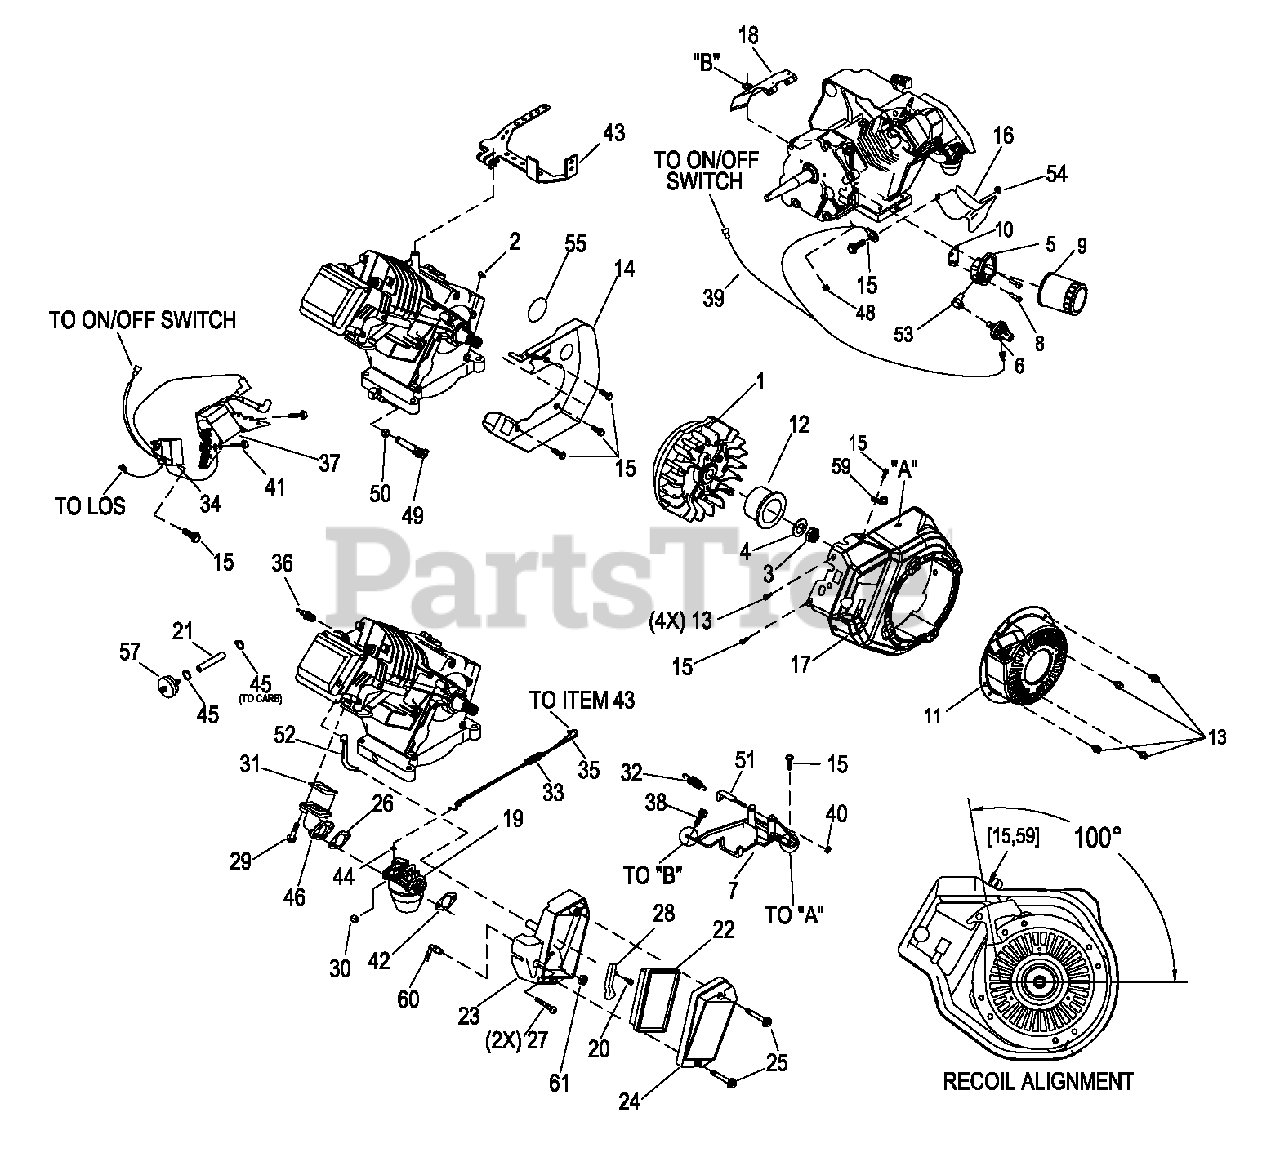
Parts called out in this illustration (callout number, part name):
1	ASSY, FLYWHEEL 29 DEGREE
2	KEY, WOODRUFF 4 X 19 DIAMETER
3	NUT, HEX M16-1.5 G8
4	WASHER, M16 CONICAL
5	ADAPTOR, OIL FILTER GH220
6	OIL PRESSURE SWITCH 5PSI
7	ASSY, BRACKET GOVERNOR ADJUSTMENT
8	SCREW, SHC M6-1.0 x 20
9	OIL FILTER BLACK 75mm LONG
10	GASKET, OIL PSI
11	ASSEMBLY, RECOIL STARTER
12	CUP, RECOIL
13	SCREW, HHTT M6-1.0 x 8
14	BACKPLATE, GH220 ELECTRIC START
15	SCREW, HHTT M6-1.0 x 10
16	WRAPPER, LOWER GH220
17	BLOWER HOUSING GH220
18	ASSEMBLY, TOP WRAPPER GH220
19	CARB, GH220 WITH CHOKE LEVER
20	SCREW, HHTT M5 – 0.8 X 12 BP
21	FUEL HOSE, 250 MM LONG
22	ELEMENT, AIR CLEANER
23	BASE, AIR CLEANER
24	COVER, AIR CLEANER
25	SCREW, HHSFC M6-1.0 x 31
26	GASKET, CARB / MANIFOLD W/O ADHESIVE
27	BOLT, CARBURETOR MOUNTING
28	COVER, BREATHER CANAL
29	SCREW, HHFC M6-1.0 x 30
30	KNOB, CHOKE LEVER, ORANGE
31	GASKET, MANIFOLD / HEAD
32	SPRING, GOVERNOR (BLUE COLOR)
33	SPRING, ANTI-LASH
34	ASSY, LOS MODULE NO LED
35	ROD, GOVERNOR GH220
36	SPARK PLUG GAP: 0.030"
37	ASSY, IGNITION COIL ADVANCED NO DIODE
38	SCREW, HHTT M8-1.2 x 16
39	WIRE HARNESS
40	NUT, HEX LOCK M5-0.5 NYLON INSERT
41	SCREW, HHTT M6-1.0 x 25 ZINC
42	GASKET, CARBURETOR / AIRBOX
43	ASSEMBLY, GOVERNOR LEVER
44	WASHER, NYLON 0.12ID x 0.28OD
45	CLAMP HOSE BAND .41
46	INTAKE MANIFOLD
48	PLUG 1/8 NPTF PIPE
49	ASSY OIL DRAIN HOSE, 4.5" LONG, ORANGE
50	CLAMP,HOSE OETIKER STPLSS 18.5
51	SCREW, GOVERNOR ADJUSTMENT
52	HOSE, BREATHER GH220
53	ELBOW 90D STREET 1/8 BRASS FRG
54	GROMMET 9/16 X 1/16 X 7/16
55	PLUG PLASTIC 1.875
57	FUEL FILTER
59	CLAMP STL/VNL .437 X .281
60	BARBED ELBOW, 90 DEGREE 1/8-27 (MODEL 05844-0 ONLY)
61	NUT, HEX 1/8-27 NPTS THIN NYLON (MODEL 05844-0 ONLY)
